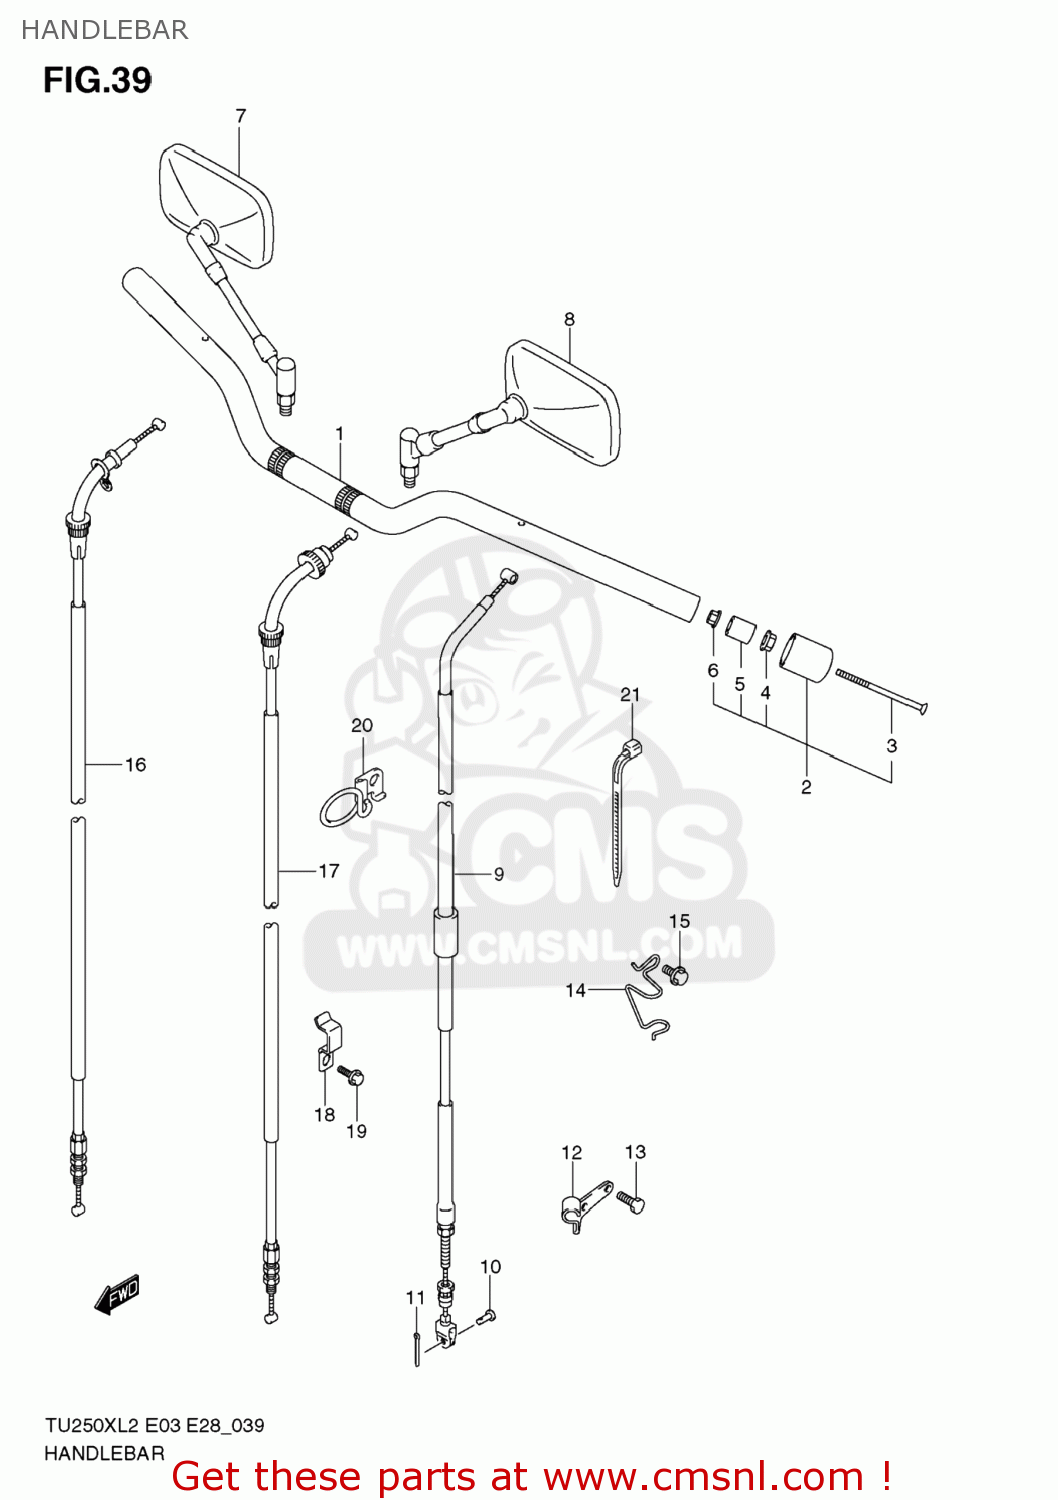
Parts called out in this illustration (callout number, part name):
1	HANDLEBAR
2	BALANCER SET,HANDLEBAR
3	SCREW
4	NUT
5	EXPANDER,HANDLE BALANCER
6	NUT
7	MIRROR ASSY,RR VIEW,R
8	MIRROR ASSY,RR VIEW,L
9	CABLE ASSY,CLUTCH
10	PIN(L:13)
11	PIN
12	STOPPER,CLUTCH CABLE
13	BOLT
14	GUIDE,CLUTCH CABLE
15	SCREW
16	CABLE ASSY,THROTTLE NO.1
17	CABLE ASSY,THROTTLE NO.2
18	CLAMP
19	BOLT
20	GUIDE,CABLE
21	CLAMP(L:190)
